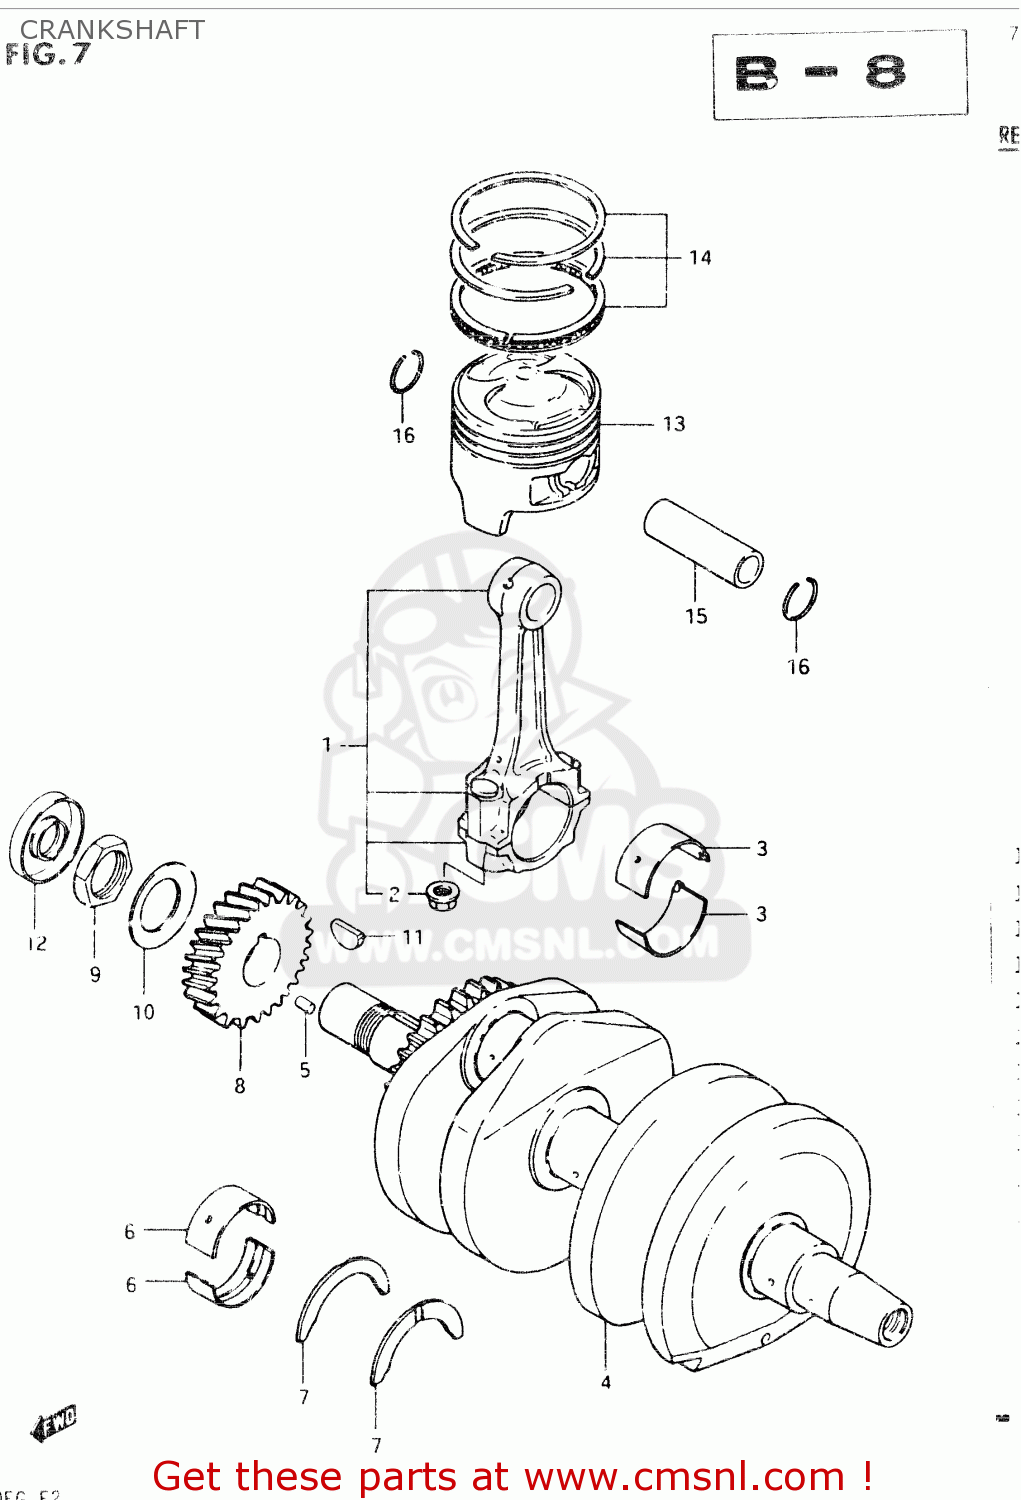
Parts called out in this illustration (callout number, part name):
1	ROD ASSEMBLY,CONNECTING
2	NUT
3	BEARING,CRANK PIN
4	CRANKSHAFT
5	PIN 3X5
6	METAL CRANKSHAFT
7	BEARING,CRANK THRUST
8	GEAR,PRIMARY DRIVE NO.28
9	NUT
10	WASHER
11	KEY
12	SEAL,OIL(22X40X8)
13	PISTON (STD)
14	RING SET,PISTON
15	PIN,PISTON
16	CIRCLIP,PISTON PIN
